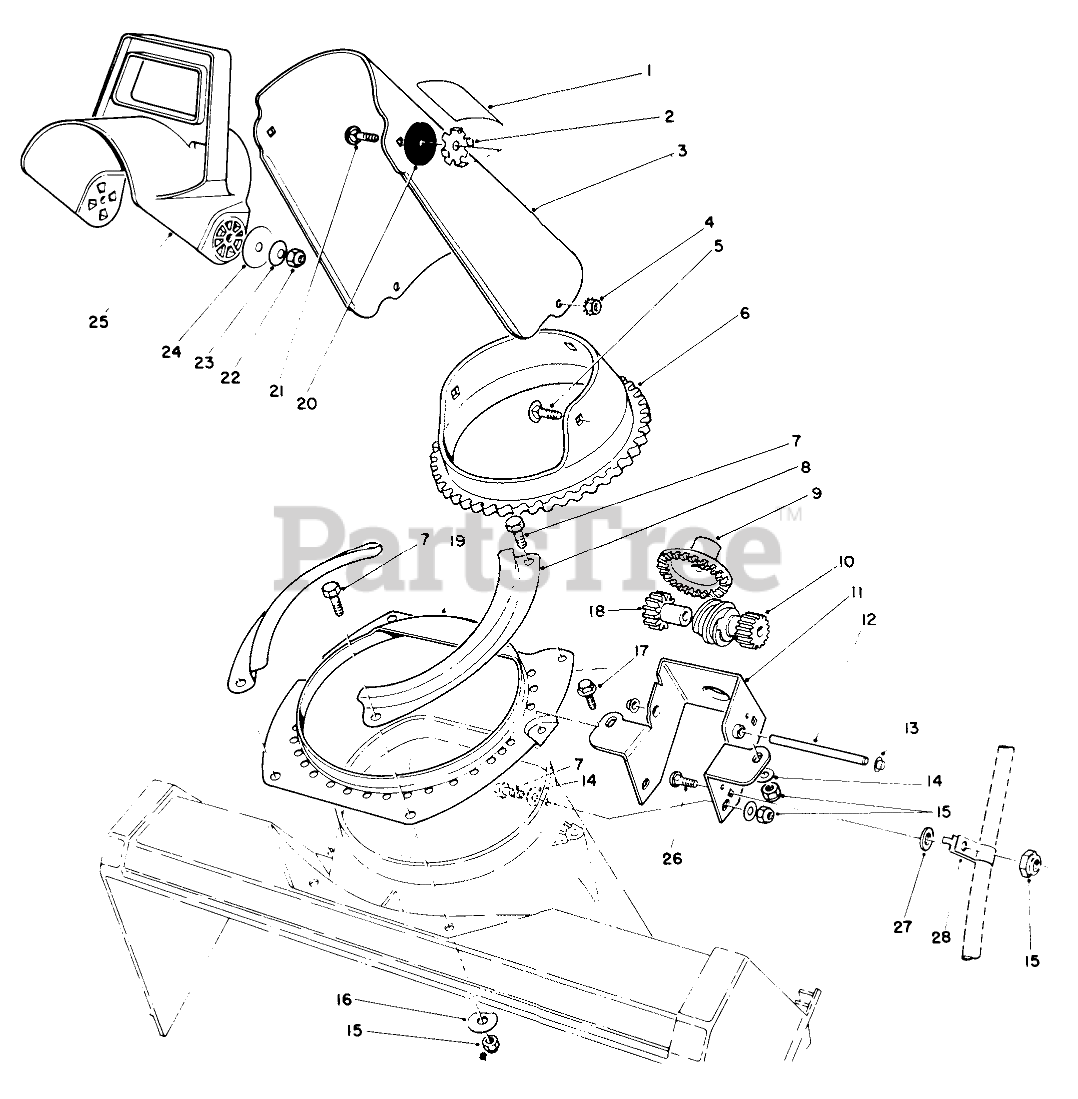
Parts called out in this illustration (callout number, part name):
1	Decal-Danger
2	PLATE-FRICTION
3	Chute-Discharge (Incl. Ref. #1)(Model #38185)
4	NUT-KEPS
5	SCREW-CARR
6	RING-GEAR, CHUTE
7	SCREW-HH
8	Retainer-Chute Ring
9	GEAR-FACE
10	GEAR-SPUR/WORM
11	Bracket-Chute Gears
12	SHAFT-GEAR, WORM
13	NUT-PUSH
14	WASHER-FLAT
15	NUT-LOCK, NI
16	Washer
17	SCREW-PLASTITE
18	GEAR-SPUR, SPACER
19	Ring-Chute Support
20	WASHER-RUBBER
21	SCREW-CARR
22	NUT-LOCK, NI
23	WASHER-BELLEVILLE
24	WASHER-FLAT
25	CHUTE-DEFLECTOR
26	SCREW-CARR
27	WASHER-PLAIN
28	ABLE CLAMP
